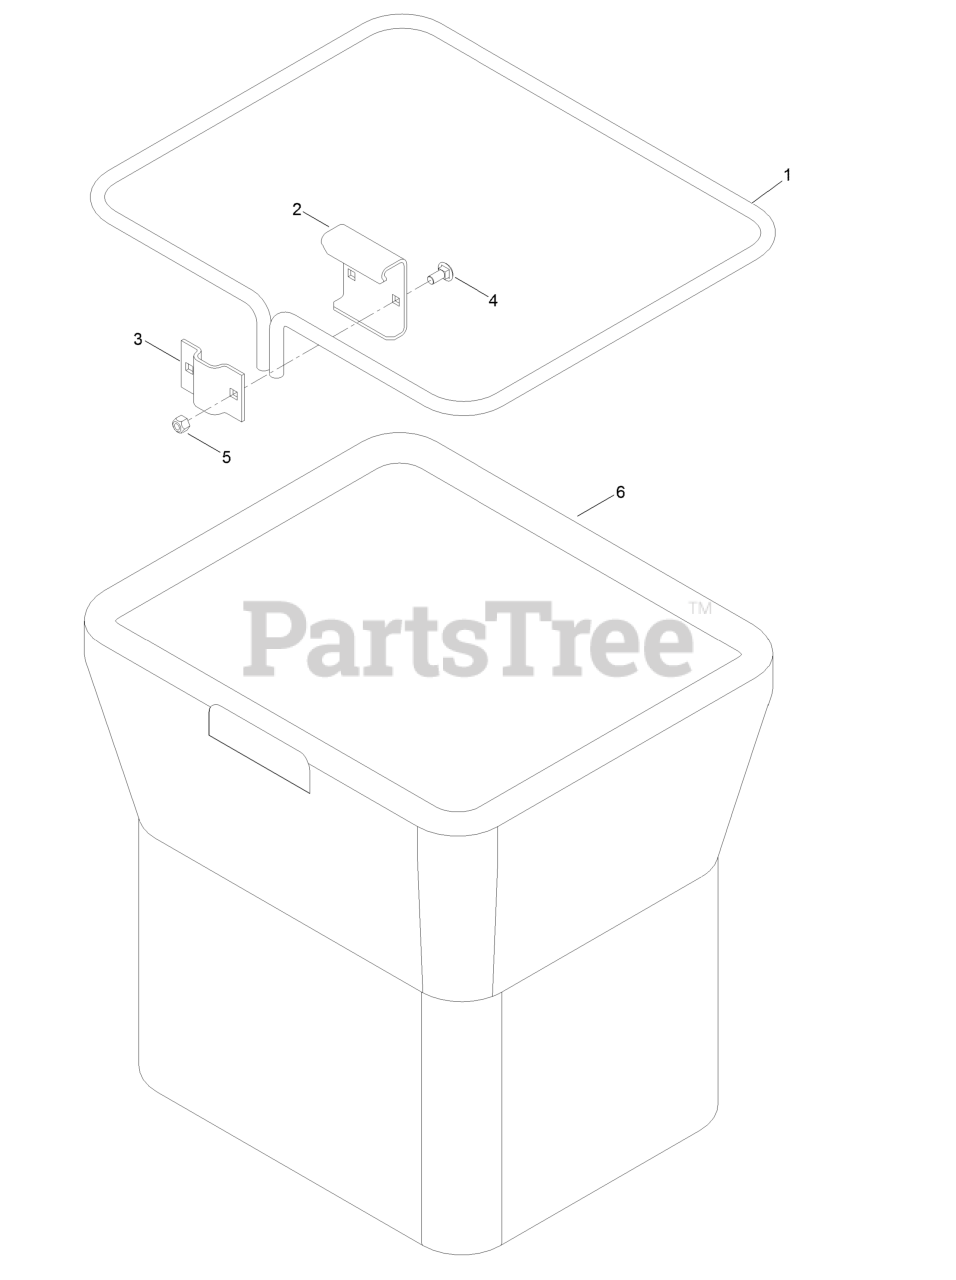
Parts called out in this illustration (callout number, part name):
1	FRAME-BAG
2	HANGER-BAG
4	BOLT-CARR
5	NUT-LOCK, NI
6	BAG
